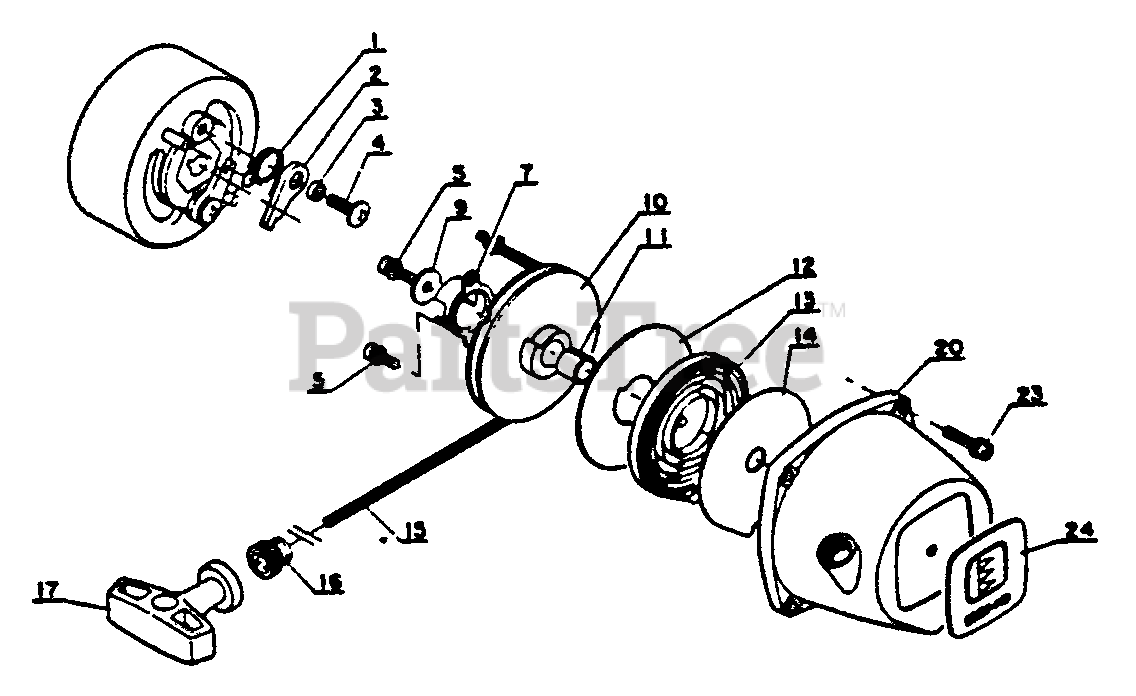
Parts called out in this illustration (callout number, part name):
1	SPRING, RETURN
2	PAWL, STARTER
4	SCREW
5	SCREW - 4X10
7	CATCHER, PAWL
10	REEL, ROPE
12	PLATE, STARTER
13	SPRING, REWIND
14	PLATE, STARTER
15	ROPE, STARTER - 3.5X850
16	GUIDE, ROPE
17	GRIP, STARTER
20	CASE, STARTER
23	SCREW - 4X20
24	LABEL - ECHO
